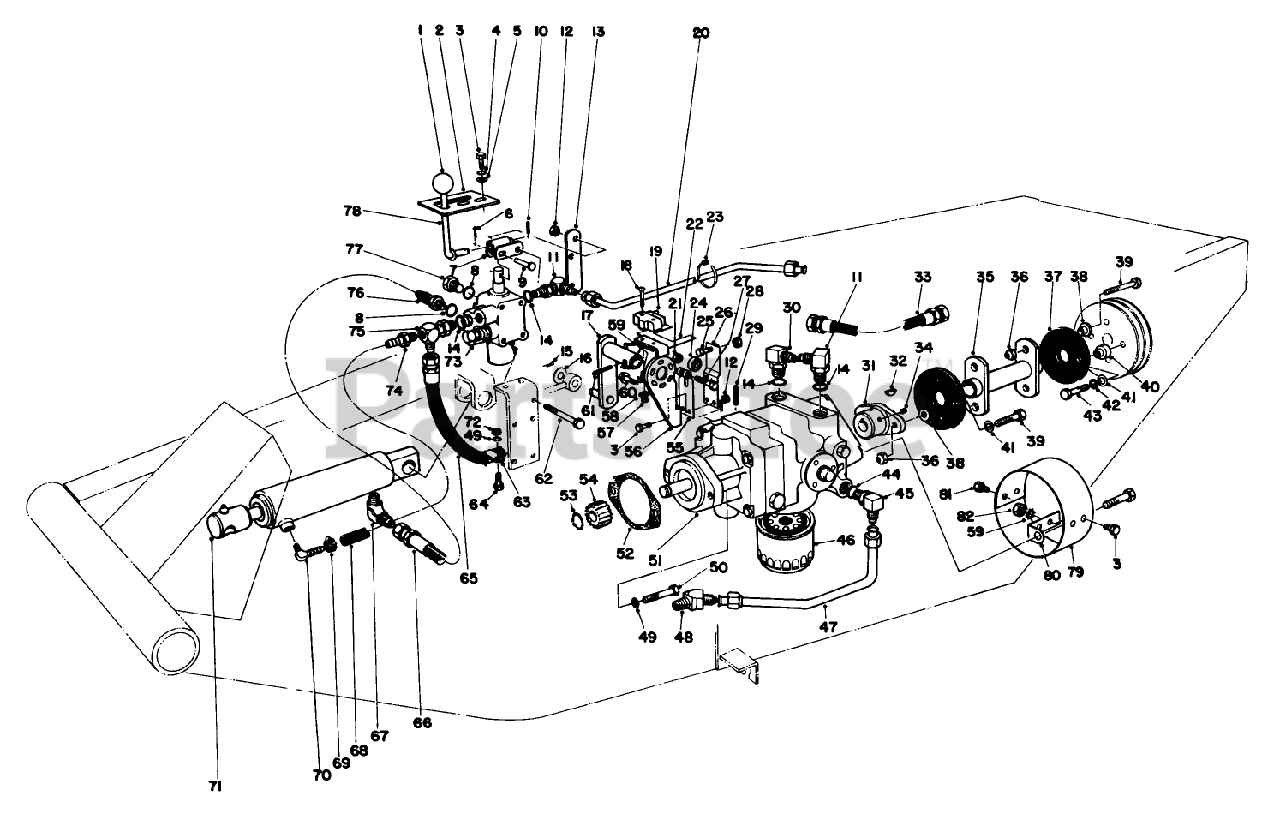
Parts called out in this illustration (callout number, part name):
2	LATCH-LEVER, VALVE
3	SCREW-HH
4	WASHER-LOCK
5	WASHER-FLAT
6	PIN-COTTER
7	Link-Valve Lever
8	O-RING
9	PIN-CLEVIS
10	PIN-ROLL
11	FITTING-ELBOW, 90 DEG
12	NUT-LOCK, NI
13	LEVER-VALVE, PIVOT MOUNT
14	O-RING
15	PIN-COTTER
16	WASHER-FLAT
17	Lever-Pump
18	SCREW-MACHINE
19	Micro Switch
20	PRESSURE LINE TUBE
21	NUT-LOCK, NI
22	STOP-SPRING, LEAF
23	TIE-CABLE
24	BEARING-BALL
25	SCREW-HH
26	EXTENDED LEAF SPRING ASM
27	SCREW-HH
28	NUT-HEX
29	PIN-ROLL, SLOTTED
30	FITTING-HYD, 90 DEG
31	HUB-PUMP
32	KEY-WOODRUFF
33	PUMP-COOLER HOSE
34	SCREW-SET
35	DRIVE COUPLING WA B
36	NUT-LOCK, CONE
37	COUPLING-RUBBER
38	SPACER-COUPLING
39	SCREW-HH
40	SPACER-COUPLING, RUBBER
41	WASHER-FLAT
42	WASHER-LOCK
43	SCREW-HH
44	O-RING
45	FITTING-ELBOW, 90 DEG
46	FILTER-OIL, TRANSMISSION
47	AXLE-PUMP TUBE ASM
48	45 DEG FITTING
49	WASHER-LOCK
50	SCREW-HH
51	Transmission Inline (Incl. Ref. #32)
52	GASKET
53	Ring-Snap
54	Gear
55	SPRING-LEAF
56	Plate-Pump
57	NUT-HEX
58	WASHER-LOCK, INTERNAL
59	WASHER-LOCK/EXT
60	Screw
61	PIN-SPRING
62	SCREW-HH
63	CLAMP-R
64	SCREW-HH
66	VALVE-CYLINDER HOSE
67	ELBOW
68	GAS LINE
69	CLAMP-HOSE
70	CONNECTOR-HOSE
71	Cylinder-Hydraulic
72	NUT-HF
73	Valve ASM
74	FITTING-STRAIGHT
75	FITTING ASM
76	FITTING-ELBOW, 90
78	Lever Valve
79	Cover
80	BRACKET-MOUNTING
81	SCREW-HH
82	NUT-HEX
